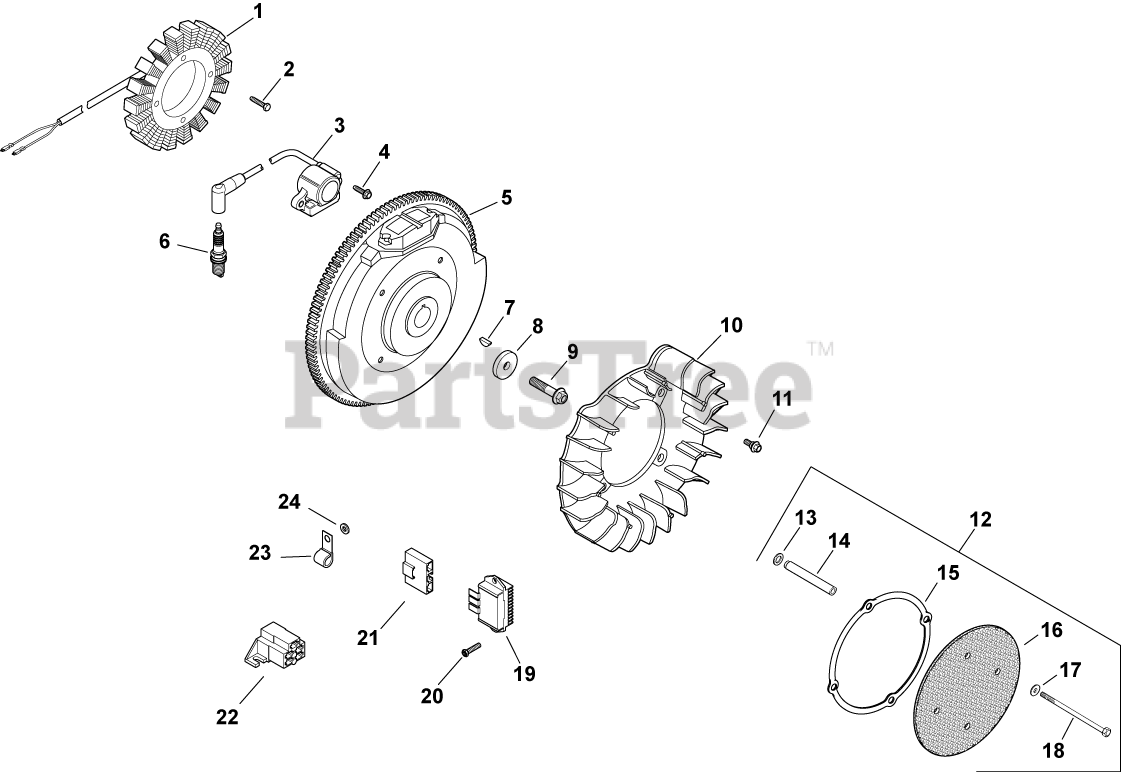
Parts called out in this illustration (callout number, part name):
1	KIT, 15 / 20 AMP STATOR
2	SCREW, M5X0.8X25 - (#25086402S)
3	KIT, MODULE IGNTN (CDI FIXED)
4	SCREW, FLG THD FRM M5X.8X20-(#25086399S)
5	FLYWHEEL ASSEMBLY
6	PLUG, SPARK (STD)
7	KEY, 3/16" X 5/8"
8	WASHER, FLAT 13/32"
9	SCREW, FLG M10X1.5X45 - (#25086361S)
10	FAN USE 24 755 253-S
11	SCREW, SKT SET #10-24X1/4"
12	KIT, CHOPPER SCREEN
13	WASHER, SPRING 10 MM
15	RING, SUPPORT USE 25 141 08-S
16	SCREEN, GRASS
17	WASHER, FLAT 1/4" (O.D. 5/8")
18	SCREW, CAP M6X1.0X99.5
19	REG/RECT-15 AMP (KM)-USE 41 403 10-S
20	SCREW, HEX FLANGE HI-LO
21	CONNECTOR
22	CONNECTOR
23	CLIP, CABLE
24	WASHER, FLAT 1/4" (O.D. 1/2")
